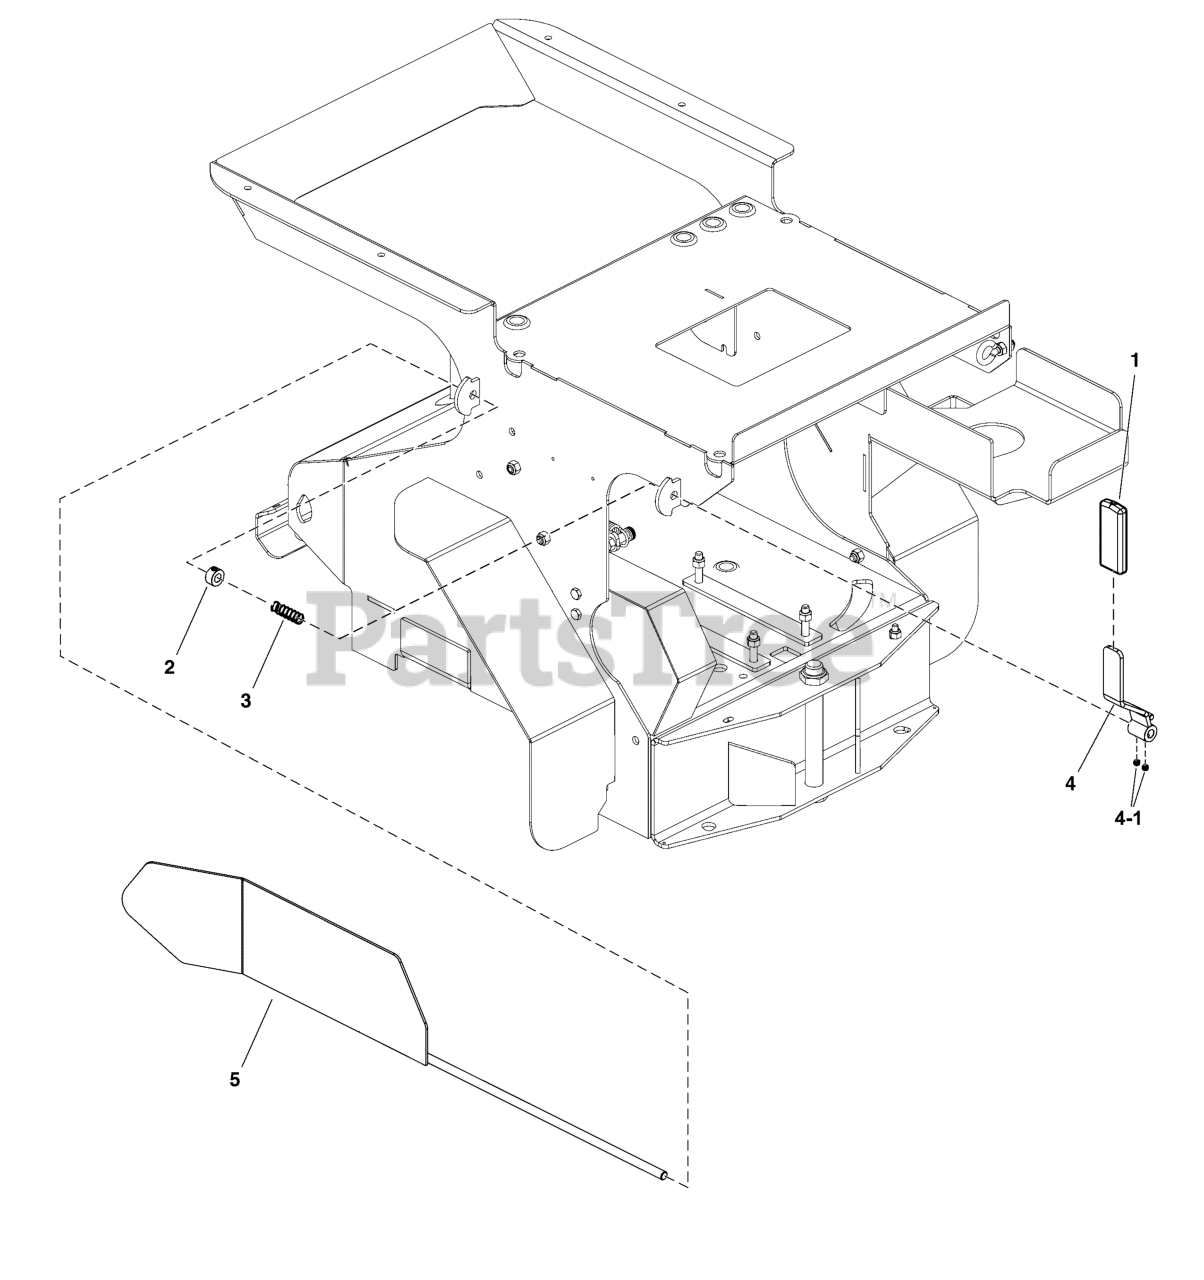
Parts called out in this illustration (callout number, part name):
1	GRIP, .188" X 1.00" ID X .150" THK CLSD CELL FOAM
2	COLLAR, SHAFT .375ID X .750OD X .375WD
3	SPRING, COMPRESSION .480" OD X 1.500 LONG SS
4	ASM, HANDLE DIVERTER W/GRIP PATHFINDER
4-1	SET SCREW, 1/4"-20 X 3/16" Hex Socket
5	WELD, DIVERTER
